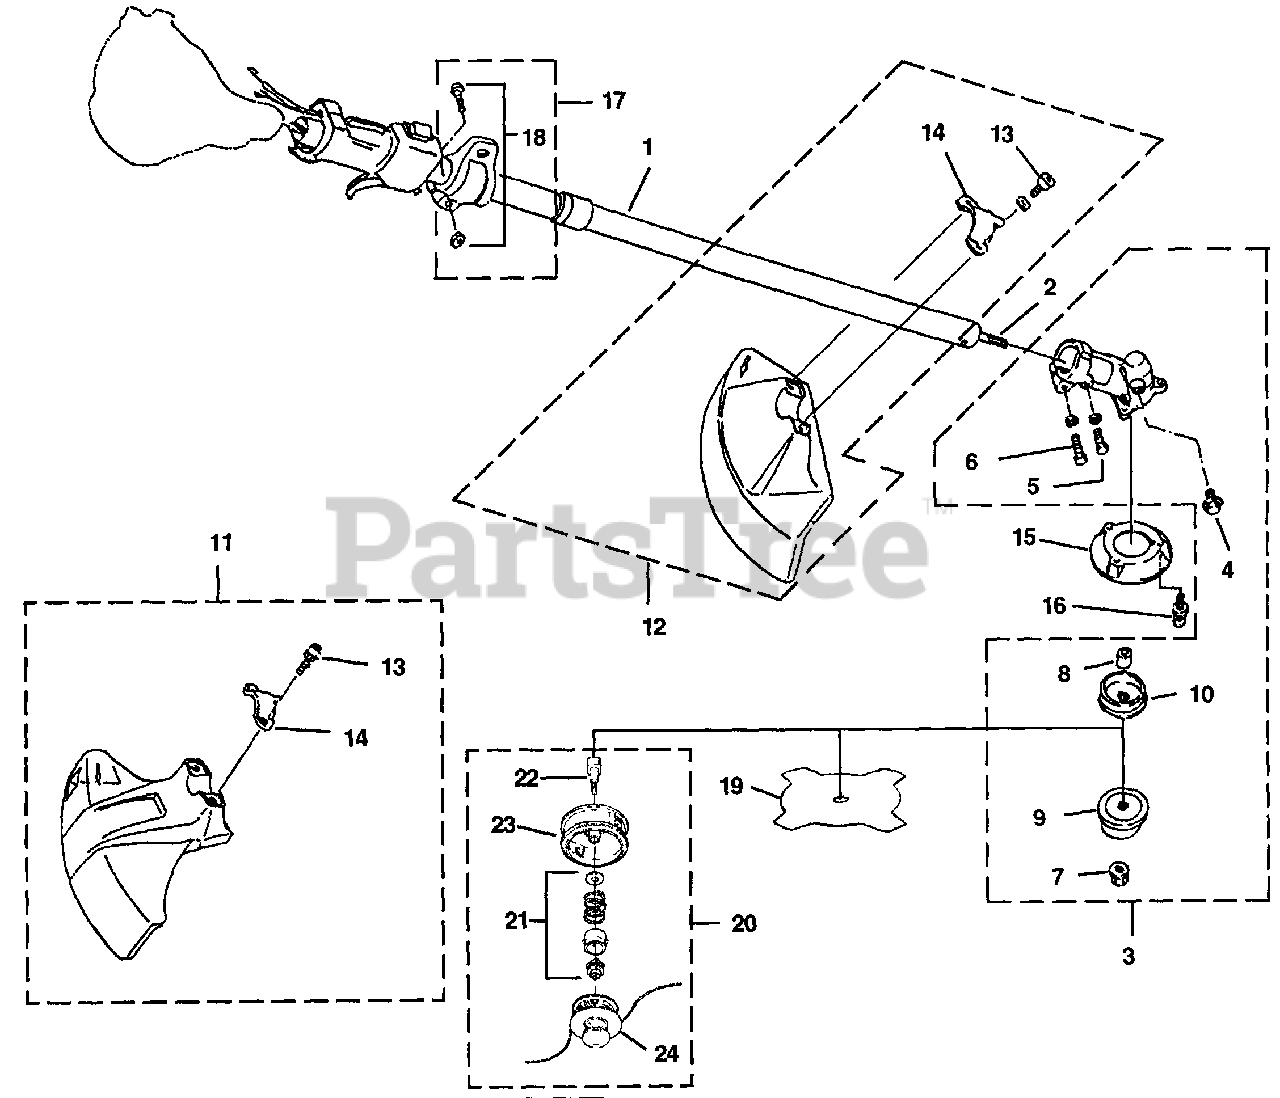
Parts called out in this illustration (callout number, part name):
1	DRIVESHAFT HOUSING
2	Drive Shaft
3	GEAR HEAD
4	BOLT-Grease
9	WASHER-Cupped
10	WASHER-Flange
11	DEFLECTOR ASSEMBLY (Grass)
12	DEFLECTOR ASSEMBLY (Blade)
13	BOLT (M6 x 30)
15	GRASS GUARD
16	SCREW-Socket Hd (M5 x 12 W SW)
17	HANGER ASSEMBLY
18	SCREW and NUT
19	QUAD BLADE
20	STRINGHEAD ASSEMBLY (.095)
21	REPAIR KIT
22	BOLT, Shaft
23	HOUSING W/Eyelets
24	SPOOL & STRING (.095)
